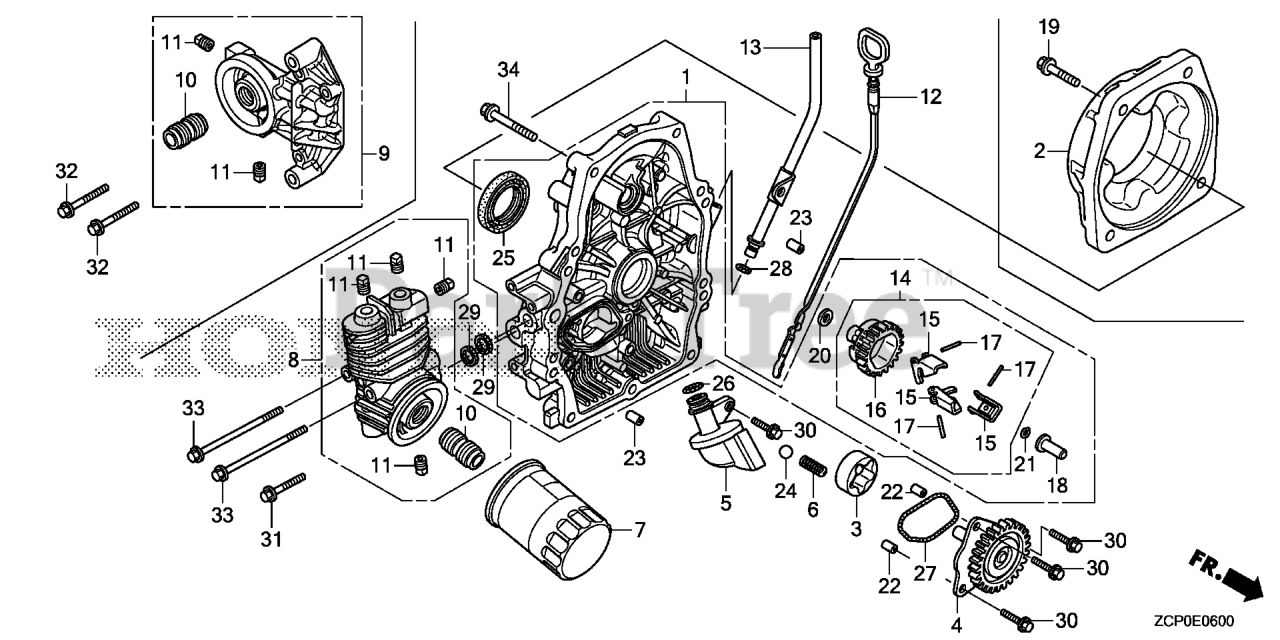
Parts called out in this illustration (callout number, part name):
1	COVER ASSY., CRANKCASE (NOT AVAILABLE)
3	ROTOR, OIL PUMP (OUTER)
4	GEAR, OIL PUMP
5	STRAINER, OIL
6	SPRING, RELIEF VALVE
7	FILTER, OIL
8	BASE, OIL FILTER
10	HOLDER, OIL FILTER
11	BOLT, SEALING
12	GAUGE, OIL LEVEL
13	PIPE, OIL LEVEL
14	GOVERNOR ASSY.
15	WEIGHT, GOVERNOR
16	HOLDER, GOVERNOR WEIGHT
17	PIN, GOVERNOR WEIGHT
18	SLIDER, GOVERNOR
20	WASHER (6X16)
21	CLIP, GOVERNOR HOLDER
22	PIN, DOWEL (8X10)
23	PIN, DOWEL (8X14)
24	BALL, STEEL (#15) (15/32)
25	OIL SEAL (38X58X9)
26	O-RING (14.8X2.4)
27	O-RING, OIL PUMP
28	O-RING (8.8X1.9)
29	GASKET, OIL PASSAGE
30	BOLT, FLANGE (6X20)
31	BOLT, FLANGE (6X28)
33	BOLT, FLANGE (6X90)
34	BOLT, FLANGE (8X45)
